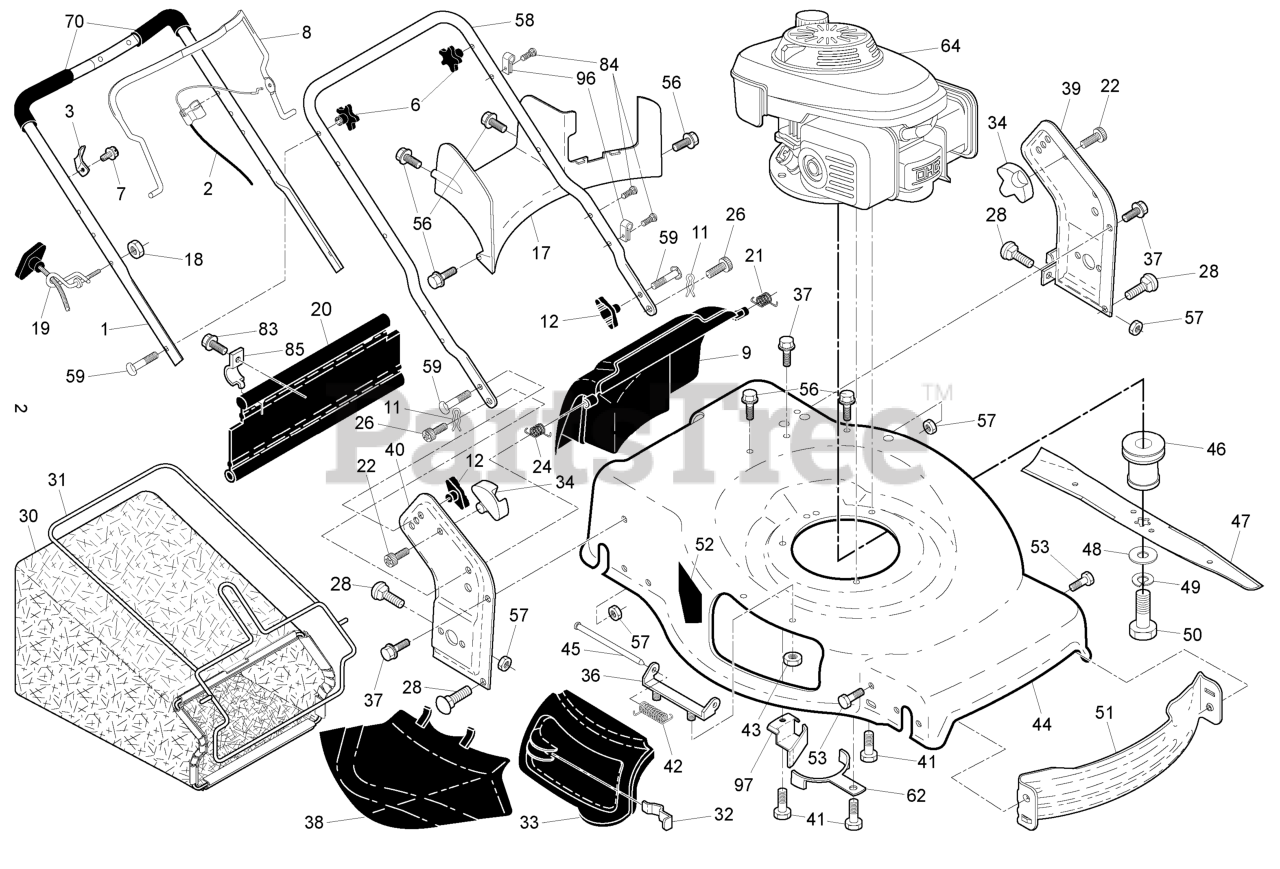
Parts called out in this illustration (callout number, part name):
1	HANDLE.ASM.UPPER.W/GRIP
2	CABLE.MZR.RGD.PLUS.ERG
3	BRACKET.UPSTOP.RT
6	KNOB.HANDLE.PLASTIC.STAR.BLACK
8	BAIL.CONTROL.MZR.BS.ORANGE
9	DOOR.REAR.ASM.22+.HUSQ.FG/RGD
11	COTTER.HAIRPIN.DOOR/HANDLE.PIV
12	KNOB, DEFLECTOR
17	RP.BAFFLE.REAR.22+.RGD.PL
18	NUT
19	RB GUIDE.ROPE.STD.BLK.ZIN WSL
20	SKIRT.REAR.22PLUS.RGD/FGD.NEW
21	SPRING.LH.BLACK
22	SCREW.PAN.HEAD.#10
24	SPRING.RH.GRAY
26	SCREW,DOOR/HANDLE.PIVOT
28	BOLT
31	RB FRAME.GBAG.22PLUS
32	Latch, Mulcher Door
33	DOOR.ASM.MULCH.22.PLUS
34	BRACKET.GRASSBAG.ATTAC
36	BRACKET.ASM.HINGE.21.FWGD.
37	BOLT.HEX.HD.WASHER.5/16-18X.75
38	DEFLECTOR.CLIPPING.22.BLACK
39	BRACKET.ASM.HANDLE.LT.22+.FG
40	BRACKET.ASM.HANDLE.RT.22+.FG
41	BOLT 3/8-16X1-1/8
42	SPRING.TORSION
43	NUT.HEX.FLANGE.1/4
44	KIT.HSG.22+RGD.MC.WO.ORG.CESYM
45	ROD.HINGE.21
46	ADPTER.BLAD.25M.VS.22PLU.STAR
47	BLADE.22PLUS
48	WASHER,HARDEN
49	LOCKWASHER
50	SCREW, HEX HD 3/8-24 X 1-3/8
51	BAFFLE.FRONT.22.PLUS
52	DANGER DECAL
53	BOLT.5/16HEX.WHS.HD
56	SCREW.HX.13X.750
57	NUT.FLANGE.5/16
58	HANDLE.LOWER.22+.BLACK
59	BOLT, HANDLE 5/16-18X1.75
62	BRACKET.KEEPER.BELT
70	GRIP.HANDLE.FOAM.WIDE.(1 SIDE)
83	TAPPING SCREW
84	FASTENER.PUSH.O.250X0.783
85	BRACKET.SKIRT.22+.BZP
96	CLIP.CABLE.BLK
97	BRACKE.BELT.GUIDE.22+
